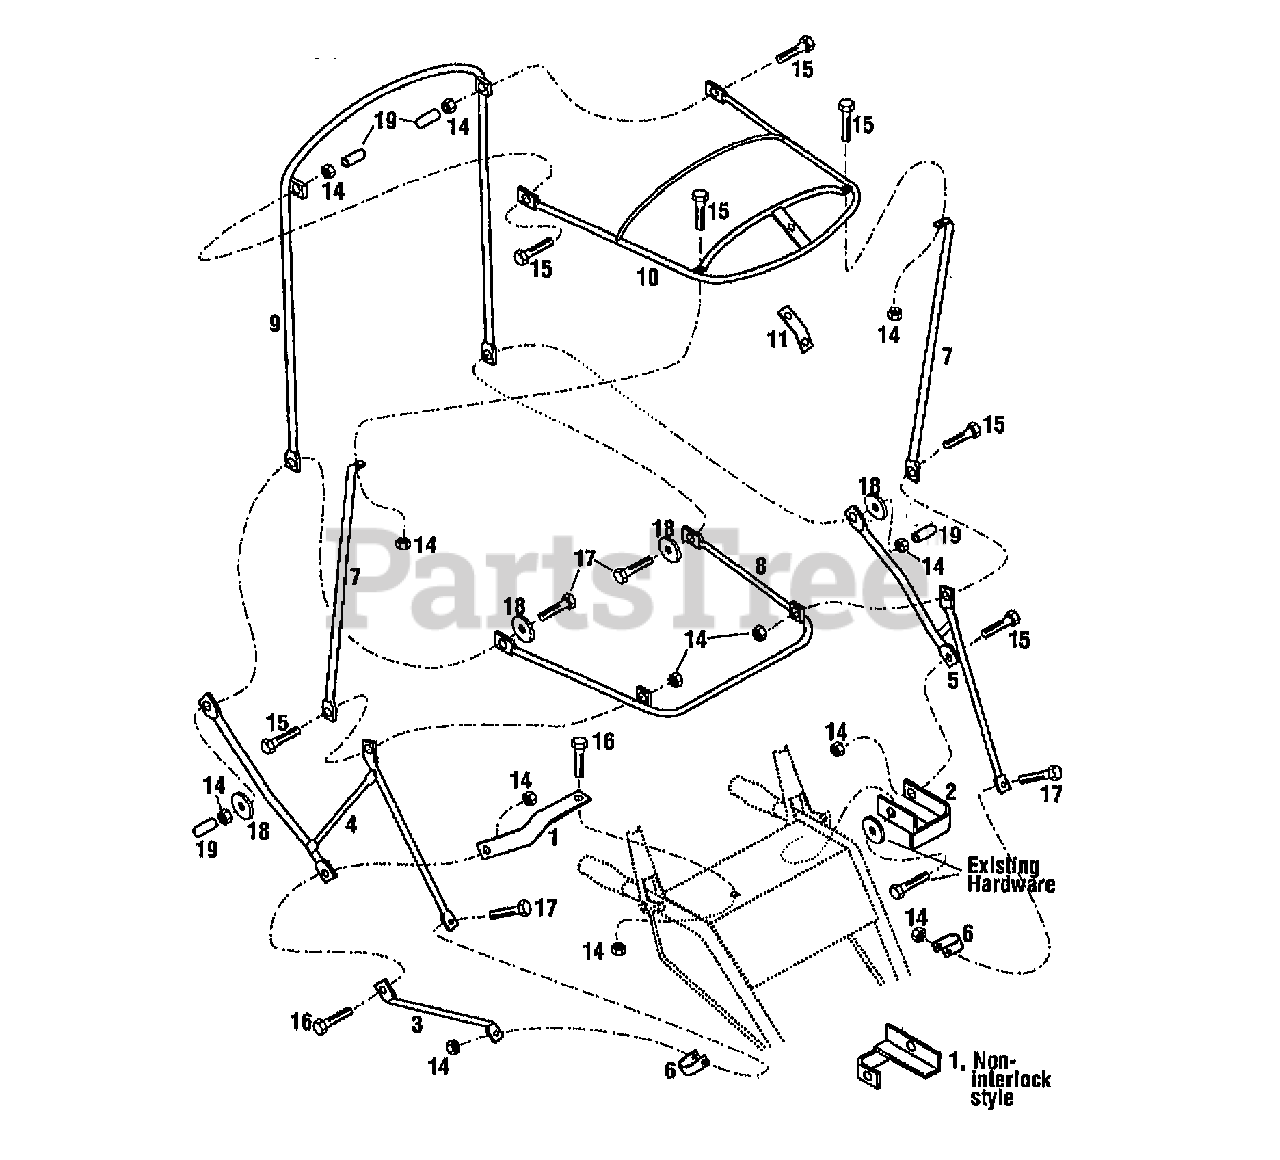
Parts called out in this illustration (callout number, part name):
1	OBS-ENG CONTROL
6	HOOD W/DECALS-H-III
7	VEST-FILSON
8	ENG MOUNTING PATTERN
9	ODD COUPLE SPECIAL
14	BOLENS OBSOLETE
